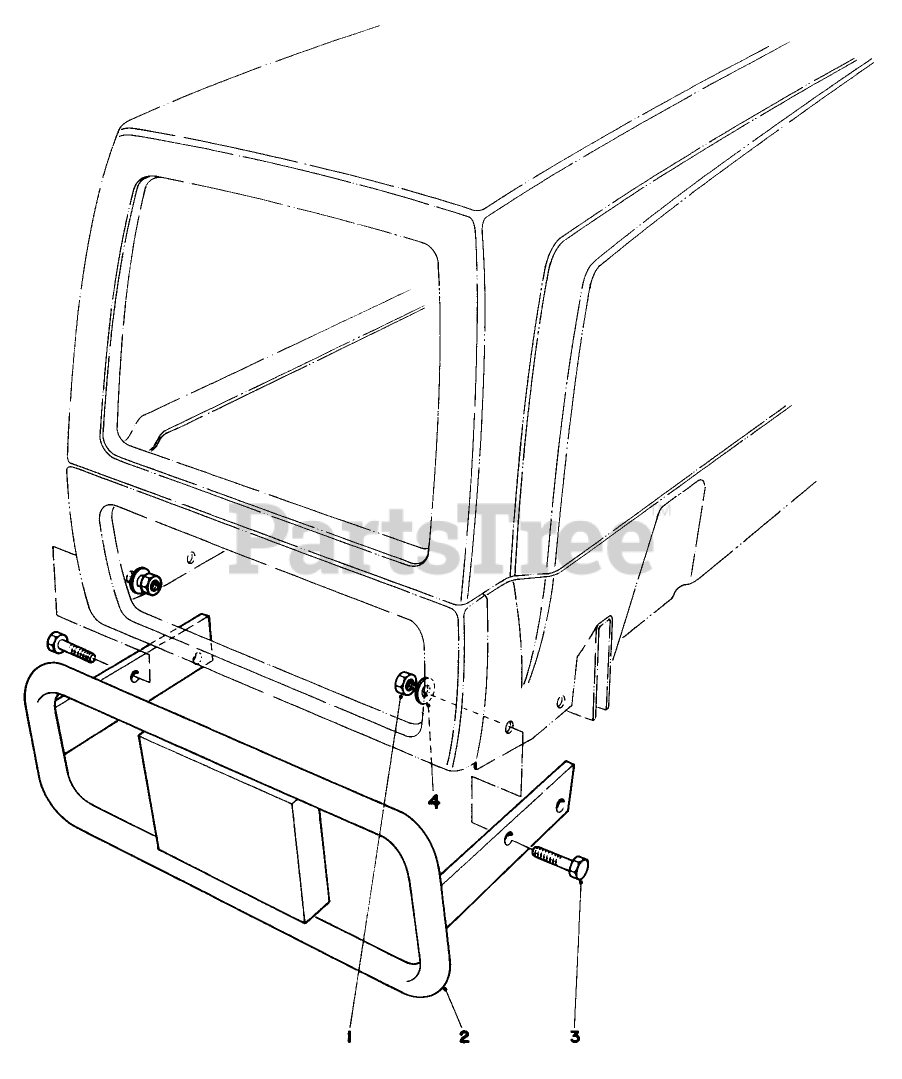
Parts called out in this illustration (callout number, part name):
1	NUT-LOCK, CONE
2	Bumper
3	SCREW-HH
4	WASHER-PLAIN
